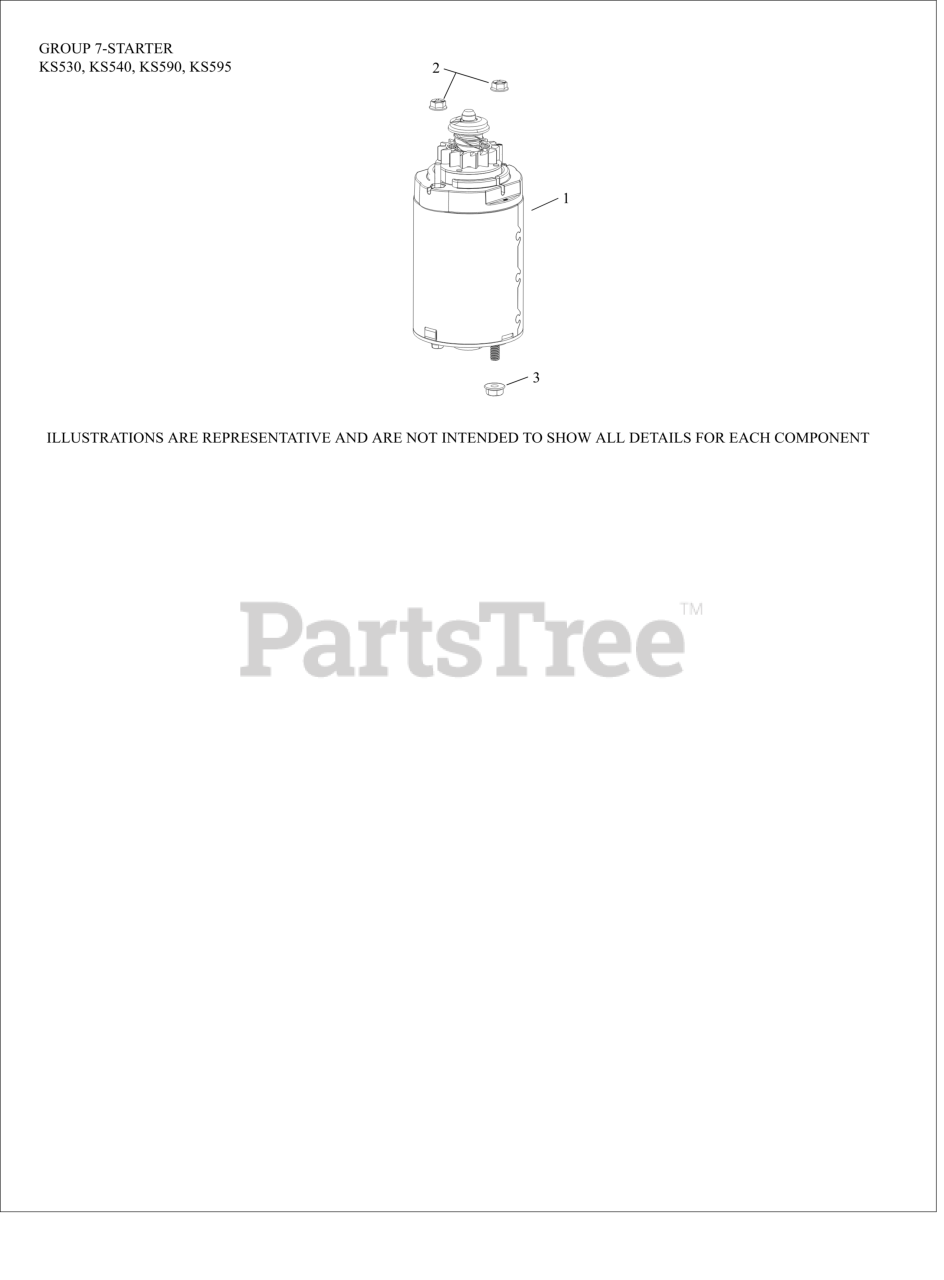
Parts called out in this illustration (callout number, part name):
1	STARTER, ASSY
2	NUT, HEX FLANGE LOCK (10-24)
3	NUT, FLANGE 1/4-20
